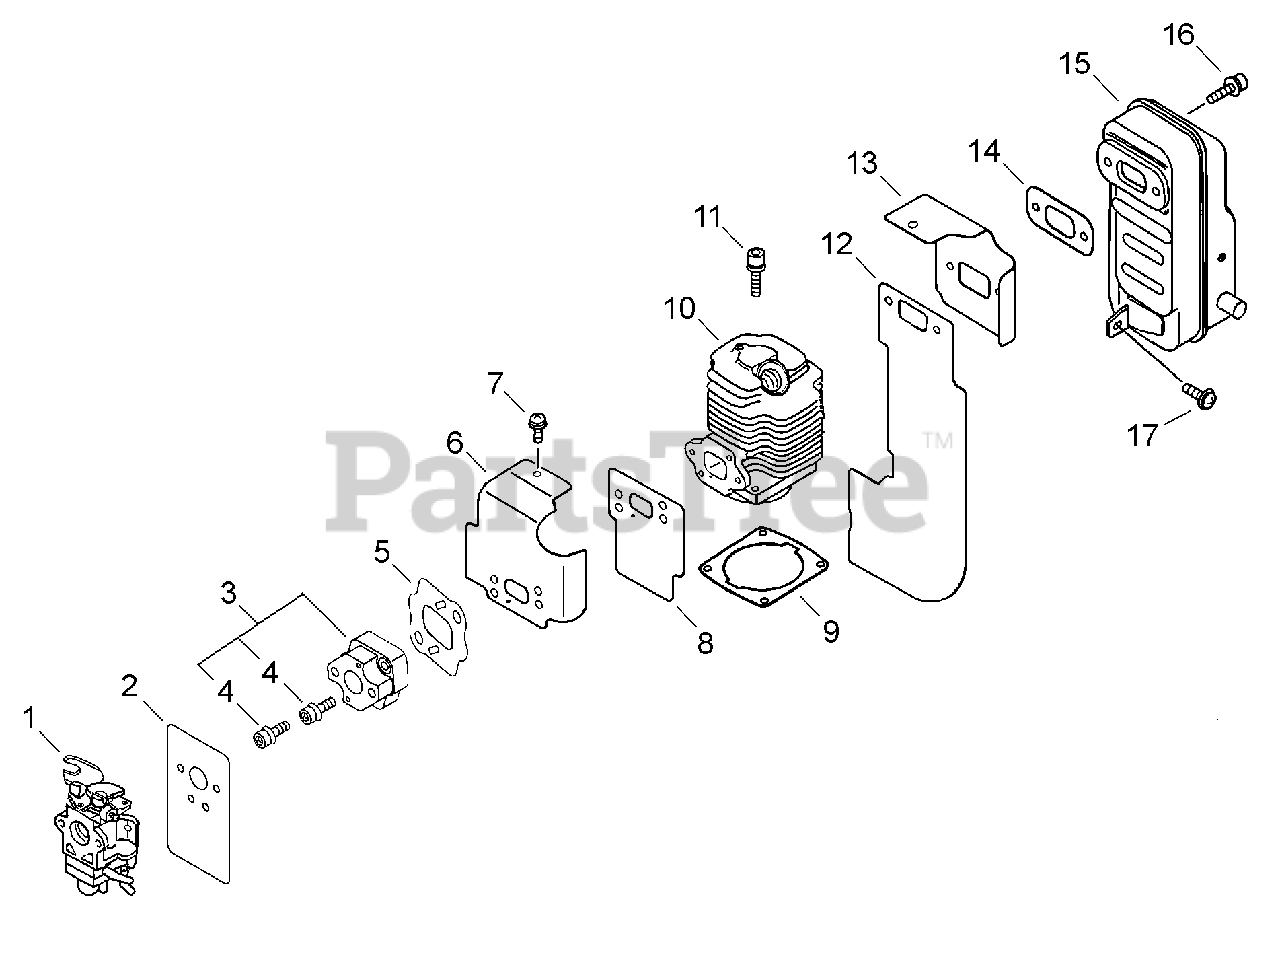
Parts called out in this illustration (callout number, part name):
1	CARBURETOR WYK-201
2	GASKET, INTAKE
3	INSULATOR KIT
4	SCREW - 5X30
5	GASKET, INTAKE
6	SHIELD, CYLINDER - INTAKE
7	SCREW - 5X10
8	SHIELD, INTAKE
9	GASKET, CYLINDER
10	CYLINDER
11	SCREW - 5X22
12	SHIELD, EXHAUST
13	COVER, CYLINDER - EXHAUST
14	GASKET, EXHAUST
15	MUFFLER ASSY
16	SCREW - 6X20
17	SCREW - 5X14
